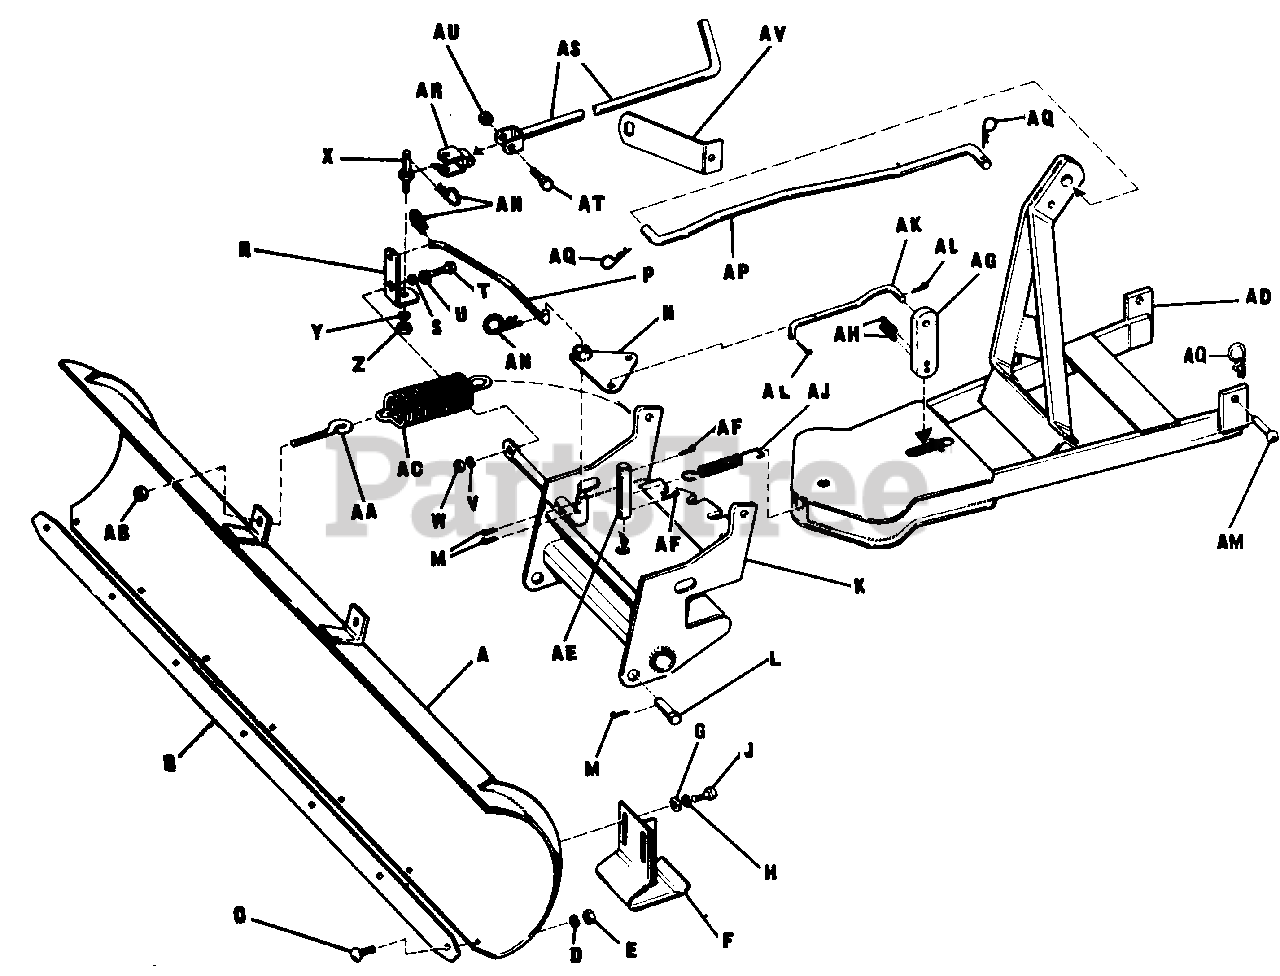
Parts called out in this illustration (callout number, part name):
A	Blade Assy.
C	Carriage Bolt, 3/8"-16 x 1" lg.
D	Lock Washer 3/8"
E	Full Hex Nut 3/8"-16 N.C.
F	Shoe Assy
G	Flat Washer 3/8"
H	Lock Washer 3/8"
J	hex. Cap Screw 3/8"-16 x 3/4"
K	Plvot Frame Assy.
M	Cotter Pln 1/8 Dia. x 1"
N	Pivot Plate Assy.
R	Pivot Arm
T	Hex Cap Screw 5/16"-18 x 1" lg.
U	Plain Washer 5/16"
V	Lock Washer 5/16"
W	Pull Hex. Nut 5/16"-18 N.C.
Y	Lock Washer 5/16"
Z	Full Hex. Nut 5/16"-18
AB	Full Hex. Nut 5/16"-18
AD	Push Bar Ass'y
AE	Pivot Pin 5/8" Dia. x 3-3/8" lg.
AF	Cotter Pin 3/16 x 1-1/4" lg.
AH	Roll Pin 7/32" Dia. x 1" lg.
AJ	Latch Spring
AL	Cotter Pin 3/32" Dia. x 5/8"
AM	(Hitch) Pin
AN	Spring Clip
AP	Front Lift-Rod
AQ	Spring Clip
AS	Handle Ass'y
AT	Hex. Cap Screw 5/16"1-18 x 1-1/2"
AU	Full Lock Hex. Nut 5/16"-18
